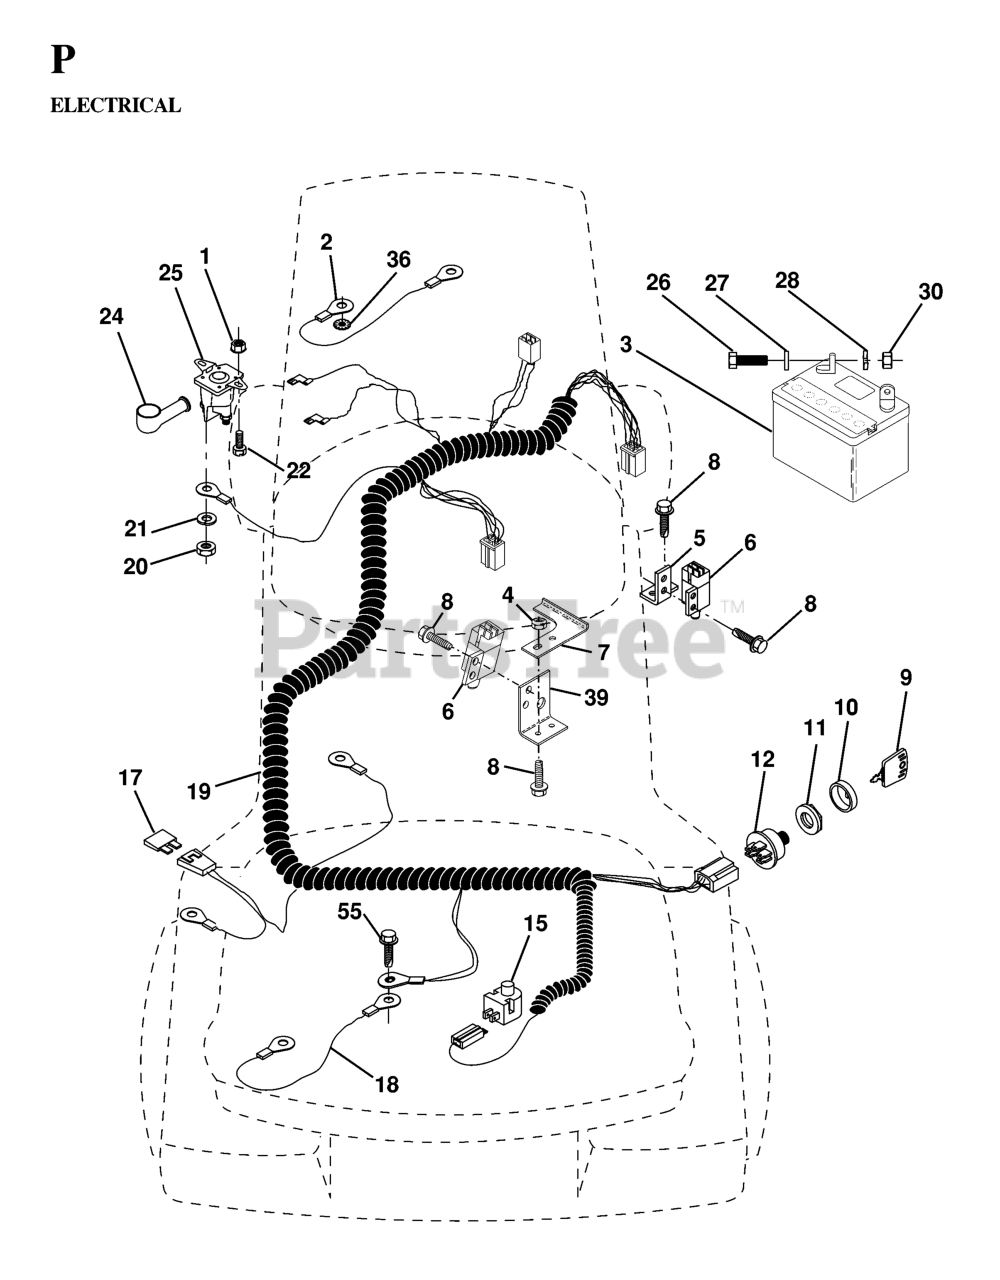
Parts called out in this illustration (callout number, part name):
1	Nut, Keps Blk Hex 1/4-20 UNC
2	CABLE.BATTERY.6GA.16"RED
3	BATTERY.DRY.30.AMP
5	BRACKET LT
6	SWITCH INTERLOCKT
7	KEEPER, ACTUAT. L.R.
9	KEY MLD GEN DELTA
10	COVER SWITCH KEY
11	NUT, IGNITION
12	IGNITION SWITCH
15	RP.SWITCH.PLUNGER.NC.GRAY
18	CABLE ASSY
19	HARNESS, IGN FEND
20	NUT
21	LOCKWASHER
22	BOLT
24	TERMINAL COVER
25	SOLINOID
26	BOLT.HEX.1/4.X.3/4.DICHROMATE
28	LOCKWASHER
30	NUT
36	Washer, Lock, Internal Tooth 1/4
55	Screw 5/16-18 x 1/2 Hex, Self Tapping 5/16-18 x 1/2
70	HARNESS, ENGINE
